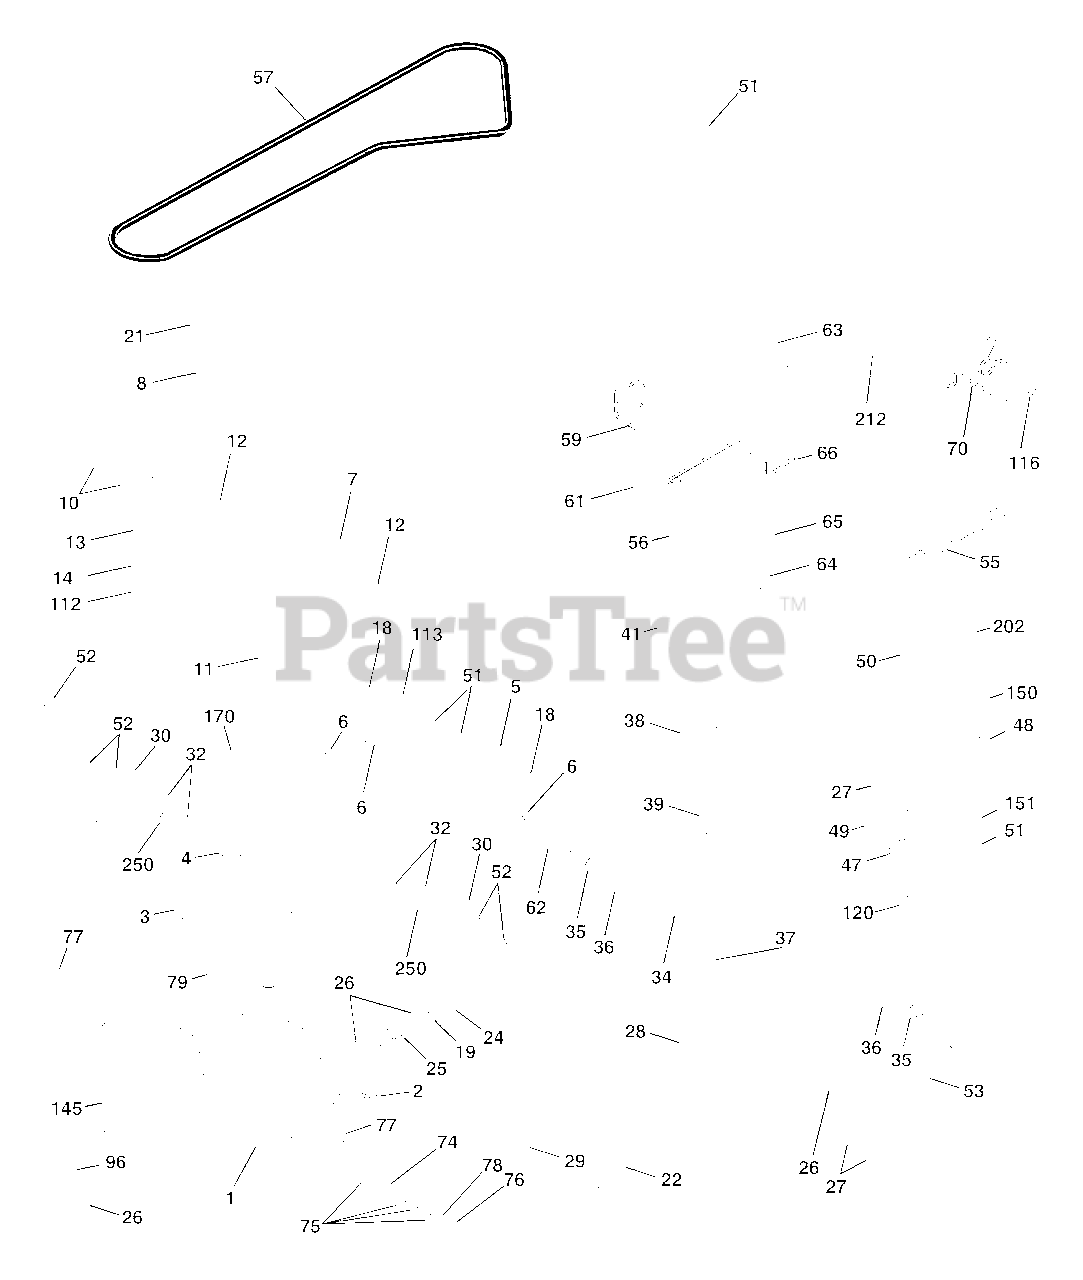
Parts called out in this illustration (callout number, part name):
2	Spring Extension Brake
3	Pulley Transaxle 18" tires
4	Ring Retainer # 5100-62
5	Strap Torque Rh Pnt Blk
6	Screw 5/16-18 X 3/4
7	Bracket T/A Saddle Shift
8	Rod Shifter Black(dana)
10	Pin,Cotter
11	Washer Plate Shf 388 Sq Hole
12	Washer 15/32 X 3/4 X 16ga
13	Bolt 1/4-28 UNF Gr. 8 W/Patch
14	Washer
18	Bolt Fin Hex 3/8-16 UNC x 1 Gr. 5
19	Nut
21	Knob Rd 1/2-13 Plstc Thds Blk
22	Rod Brake Lt
24	Nut
25	Spring Rod Brake 2 00 Zinc
26	Washer
27	Pin
28	Rod Brake Parking
29	Cap Parking Brake
30	Bracket Transmission
32	Bolt
34	Shaft Asm Pedal Foot
35	Bearing Nylon Blk 629 Id
36	Washer
37	Roll Pin
38	Pulley Idler Composite
39	Bolt Fin Hex 3/8-16 Unc x 3
41	Keeper Belt Idler
47	Pulley Idler V Groove Plastic
48	Bellcrank Clutch
49	Retainer Belt Style Spring
50	Bolt
51	Nut
52	Nut
53	Link Clutch 7 66
55	Spring Return Clutch 6 75
56	Screw 3/8-16 x 1-1/4
57	V-belt Ground Drive 95
59	Keeper Belt Chassis Span Ctr.
61	Screw 3/8-16 x .875
62	Cover Pedal Blk Round
63	Pulley Engine
64	Bolt, Hex 7/16-20 x 4 Grade 5
65	Washer, Lock, Hvy Hlcl Spring 7/16
66	Keeper Belt Engine Flproof
70	Guide Belt Dr Mower Rh
74	Spacer Axle
75	Washer 25/32 X 1 1/4 X 16 Ga
76	E Ring
77	Key Square 2 0 X 1845/ 1865
78	Washer 25/32 X 1 5/8 X 16ga
79	Key Woodruff
96	Retainer Spring 1"
112	Washer 9/32 X 3/4 X 10 Ga
113	Strap Torque Lh
116	Bolt, Rdhd Sqnk 3/8-16 x 1.00
120	Nut Lock Flg 3/8-16
145	Bolt Hex Flghd 5/16-18 x Gr. 5
150	Spacer Retainer
151	Washer 13/32 x 2 x 10 Ga.
170	Keeper Belt
212	Nut Hex Flange Lock
250	Screw 3/8-16x3/4
